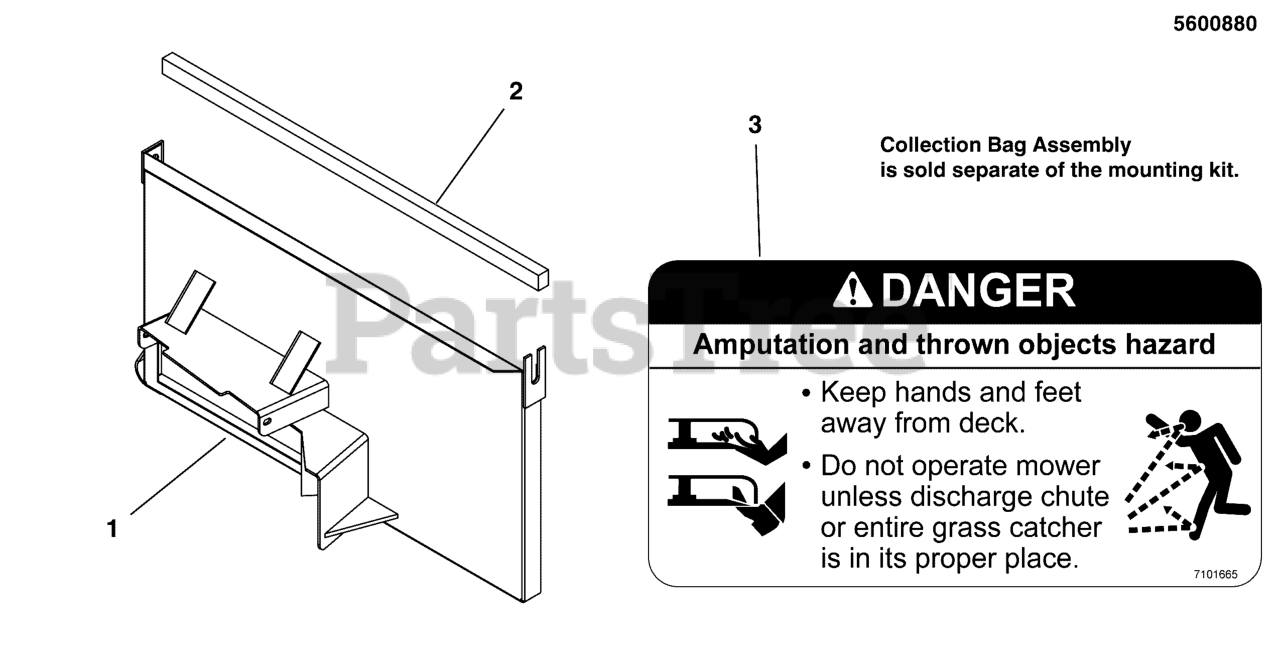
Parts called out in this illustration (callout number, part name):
1	WELD, BAGGER MOUNT, 36 - BLK
2	FOAM, 3/4 X 1 X 28.25
3	DECAL, DANGER DO NOT OPERATE W/O DEFLECT
